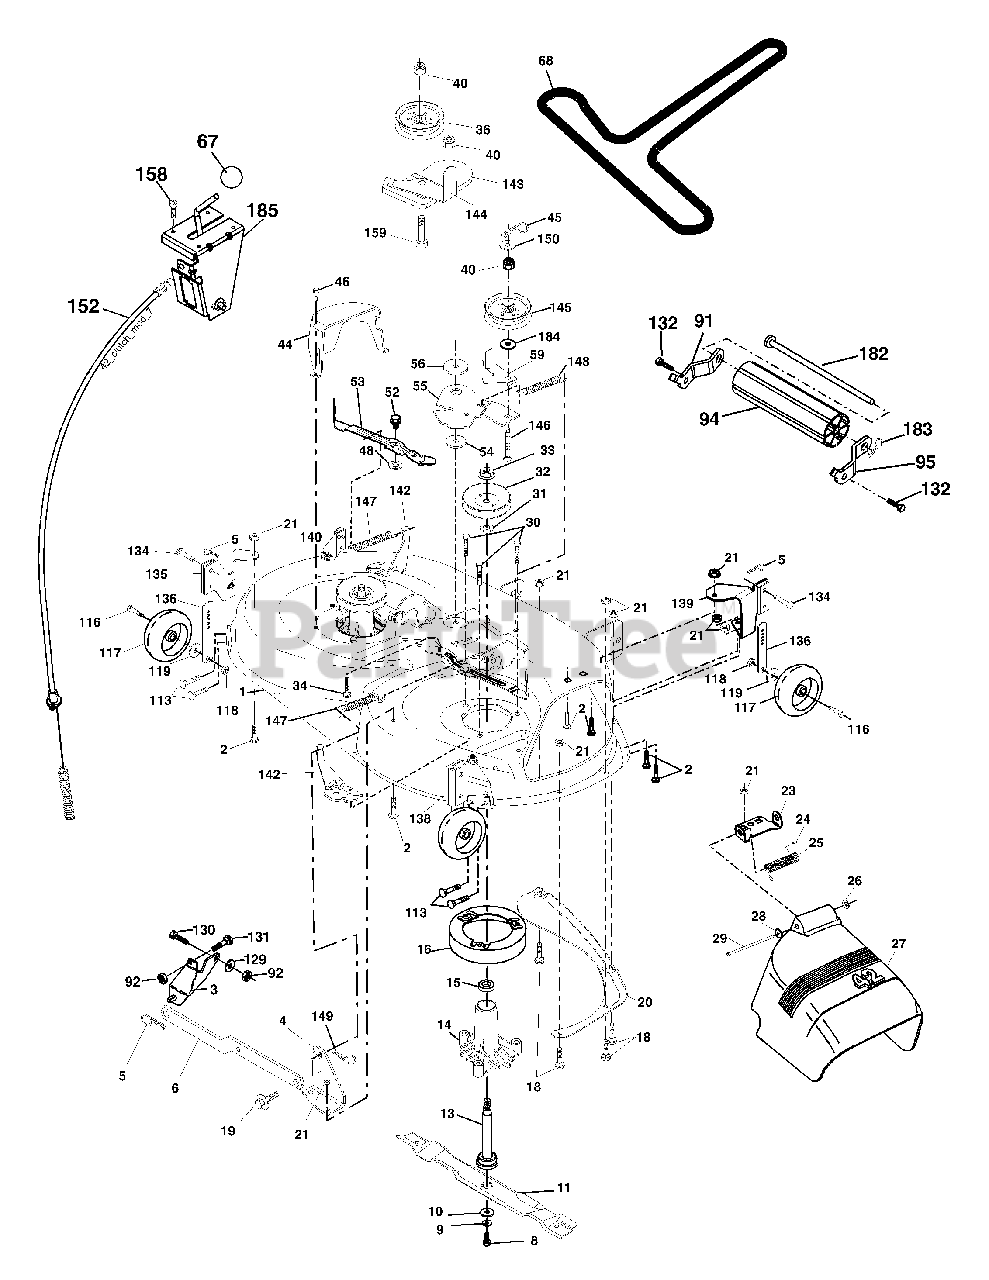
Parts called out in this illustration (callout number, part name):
1	Deck Asm 42"weldment
2	Bolt Rdhd Sqnk 5/16-18 unc x 3/4
3	Bracket Asm Fr Sway Bar 38/42
4	Bracket Asm Deck 42"sway Bar
5	Retainer Spring
6	Deck Sway Bar
8	Bolt 3/8 - 24 x 1.25 Gr. 8
9	Washer Lock Hvy 3/8
10	Washer Hard Blade Mower Vented
11	Blade, 42"
11	Blade, 42" Mulching Premium
11	Blade, 42" Hi-Lift
13	Shaft Asm W/lower Bearing
14	Housing Mandrel Vented
15	Bearing Ball Mandrel
16	Stripper Mower
18	Bolt Rdhd Sqnk 5/16-18 x 5/8
19	Bolt Shoulder
20	Baffle Vortex 42
21	Nut Crownlock 5/16-18 unc
23	Bracket Deflector Mower 42"
24	Cap Sleeve 80x 112 Blk Mower
25	Spring Torsion Deflector 2 52
26	Nut Push Phos & Oil
27	Shield Deflector Mower 42" Blk
28	Washer 11/32 x 5/8 x 16 Ga.
29	Rod Hinge 42"6 75 Wlg
30	Screw Thd Rolling
31	Washer Spacer
32	Pulley Mandrel 42"
33	Nut Toplock Flng
34	Bolt Carr Sh. 3/8-16 x 1-1/2 Gr. 5
36	Pulley Idler Flat
40	Nut Lock Flg 3/8-16 unc
44	Guard Mandrel LH Black
45	Spring Retainer 1" Zinc/cad
46	Screw Hex Thd Cut 1/4-20 x 5/8 T
48	Washer Hardened Smaller
52	Bolt Shoulder 5/16-18 unc Blkz
53	Arm Asm Pad Brake
54	Washer Hardened
55	Arm Idler 42"mower LT/YT
56	Spacer Retainer Mower
59	Guard TUV Idler
67	Knob Rd 3/8-16 Plstc Thds Blk
68	V-Belt Mower 42"
91	Bracket Asm Noseroller LH
92	Nut 3/8-16 unc
94	Roller Nose 38 & 42
95	Bracket Asm Noseroller RH
113	Screw 5/16-18 x 3/4
116	Bolt Shoulder 3/8-16 x 3-5/8
117	Wheel Gauge Donut Wide
118	Nut Centerlock 3/8-16
119	Washer 3/8 x 7/8
129	Washer 13/32 x 13/16 x 12 Ga.
130	Bolt 3/8-16 x 1 Gr.5
131	Bolt 3/8-16 x 1
132	Screw 3/8-16 x .75
134	Pin Head Rivet
135	Bracket Asm Whl Ga. Rear LH
136	Bar Adjusting Gauge Wheel
138	Bracket Asm Whl Ga. Rear RH
139	Bracket Asm Whl Ga. Front Rh
140	Bracket Asm Whl Ga. Front LH
142	Arm Spring Brake Mower
143	Bracket Arm Idler 42"
144	Keeper Belt 42" Clutch
145	Pulley Idler Flat
146	Bolt Carriage Idler
147	Spring Extension
148	Spring Return Idler
149	Retainer Spring Yellow
150	Washer 9/32 x 3/4 x 10 Ga.
152	Clutch Cable 42"
158	Screw Hex Thd Cut 1/4-20 x 1/2
159	Bolt Rdhd Sqn 3/8-16 unc x 1-3/4
182	Rod Roller Nose Std.
183	Retainer Spring
184	Washer 13/32 x 7/8 x 10 Ga.
185	Head Asm Cable Clutch
